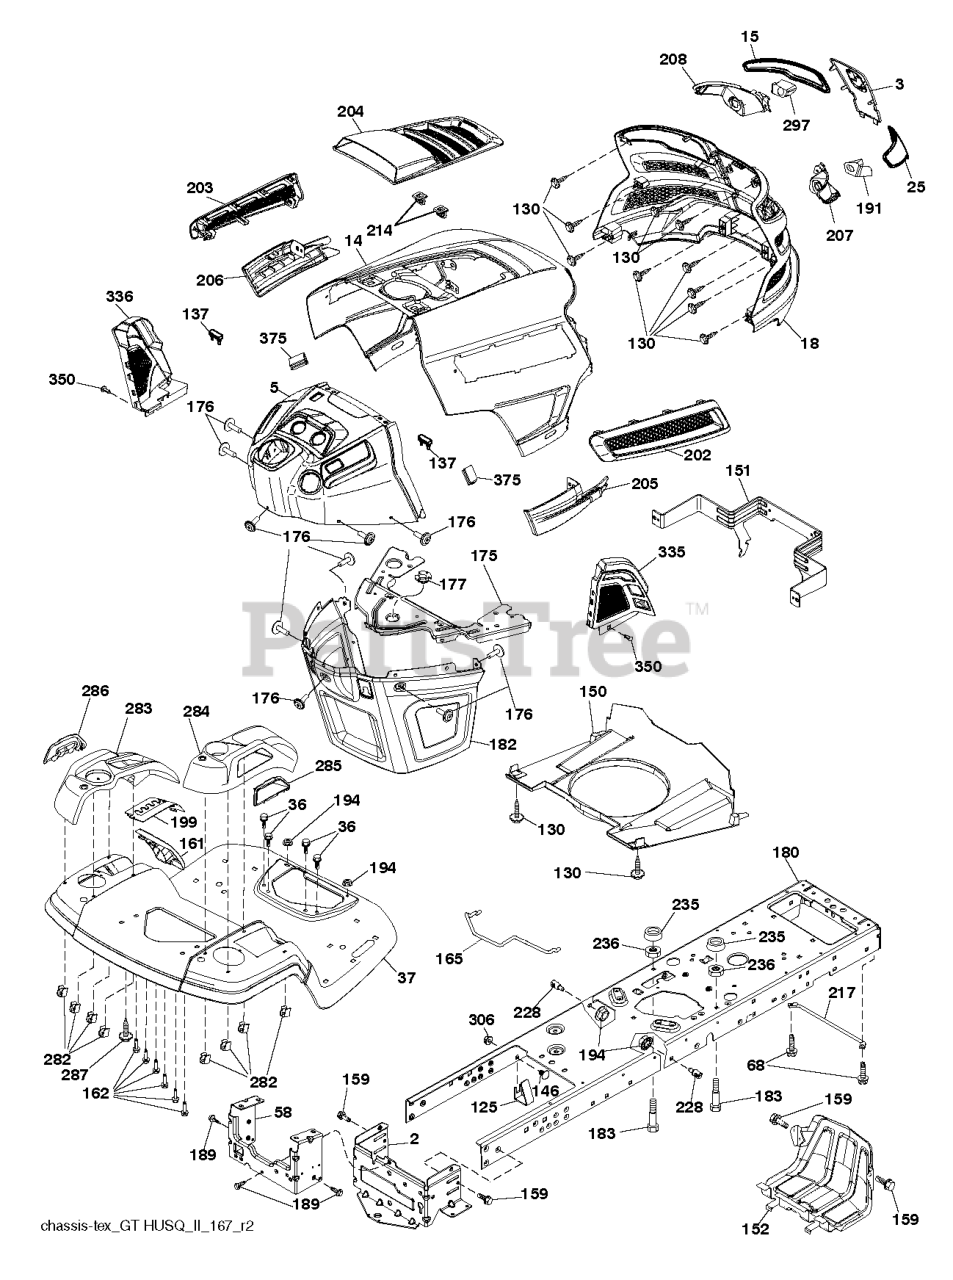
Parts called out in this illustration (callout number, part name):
2	DRAWBAR.LOWER.2PC.18/22
3	APPLIQUE.SUBASM.GT.HUSQ.II
5	DASH
14	HOOD.ASM.HUSQVARNA.GT.TEX.ORAN
15	LENS.HEADLIGHT.LH.GTII.2011
18	GRILLE.SUBSTRATE.2011.
25	LENS.HEADLIGHT.RH.GTII.2011
36	SCREW 5/16"
37	FENDER.TLT.FS.W/CPH/FW/RSF.668
58	DRAWBAR UPPER 2PC SMALL FENDER
68	Screw 5/16-18 x 1/2 Hex, Self Tapping 5/16-18 x 1/2
125	CLIP.FUEL.LINE
130	SCREW.#10 X 0.750.BOS
137	BUMPER DASH
146	BOLT.RDHD.SHT.SQNK.3/8-16X5/8
150	AIR.DUCT.GTV.BLACK
151	BRACKET.PIVOT.HOOD.GT.HUSQ.II
152	SHIELD.BROWNING.PNT.GT.V2
159	SCREW, 3/8-16X3/4
161	WINDOW.FUEL.LT.HUSQ.TEX.418
162	SCREW.HI-LO.CONSOLE
165	SUPPORT.TANK.REAR.B/TE
175	PLATE.CROSSMEMBER.HUSQ
176	SCREW.#10-24X5/8.RN.QU
177	BUSHING STEERING
180	CHASSIS.TEX.BOLTED
182	DASH.LOWER.COMMON.12V.ADAPTOR
183	BOLT.5/16-18X1-1/4 FULL THD
189	SCREW
191	INSERT.REFLECTIVE.RH.HUSQ.GTII
194	NUT LOCK HEX FLANGE 5/16-18
199	PLATE.DECK.LIFT.HUSQ.LT
202	VENT.SIDE.RH.GT.HUSQ.II.
203	VENT.SIDE.LH.GT.HUSQ.II.498
204	VENT.TOP.HUSQ.GT2
205	SIDE.TRIM.RH.GT.HUSQ.II
206	SIDE.TRIM.LH.GT.HUSQ.II.GRAY
207	BEZEL LIGHT.RH.GT.II.MYLAR
208	BEZEL LIGHT.LH.GT.II.MYLAR
214	CLIP.RETAINER.TINNER.
217	ROD.PIVOT.HOOD
228	STUD.FASTNER.W/ANTI-ROTATE
235	SPACER FENDER
236	NUT.CENTERLOCK.5/16-
282	CLIP.RETAINER.CONSOLE.LT.HUSQ
283	CONSOLE.DECK.LIFT.R.SDFL.HUSQ
284	CONCOLE.CNTRL.PDL.HUSQ.LT.498
285	CONSOLE INSERT RH
286	CONSOLE.INSRT.LH.HUSQ.LT.BLACK
287	SCREW 1/4X20
297	INSERT.REFLECTIVE.LH.HUSQ.GTII
306	NUT LOCK FLG 3/8-16 UNC
335	COVER.LOWER.DASH.RH.BLACK
336	COVER-LH.LOWER.DASH.GT2.BLACK
350	CLIP.X-MAS.TREE
375	BUMPER CLIP-ON. DASH 1"
